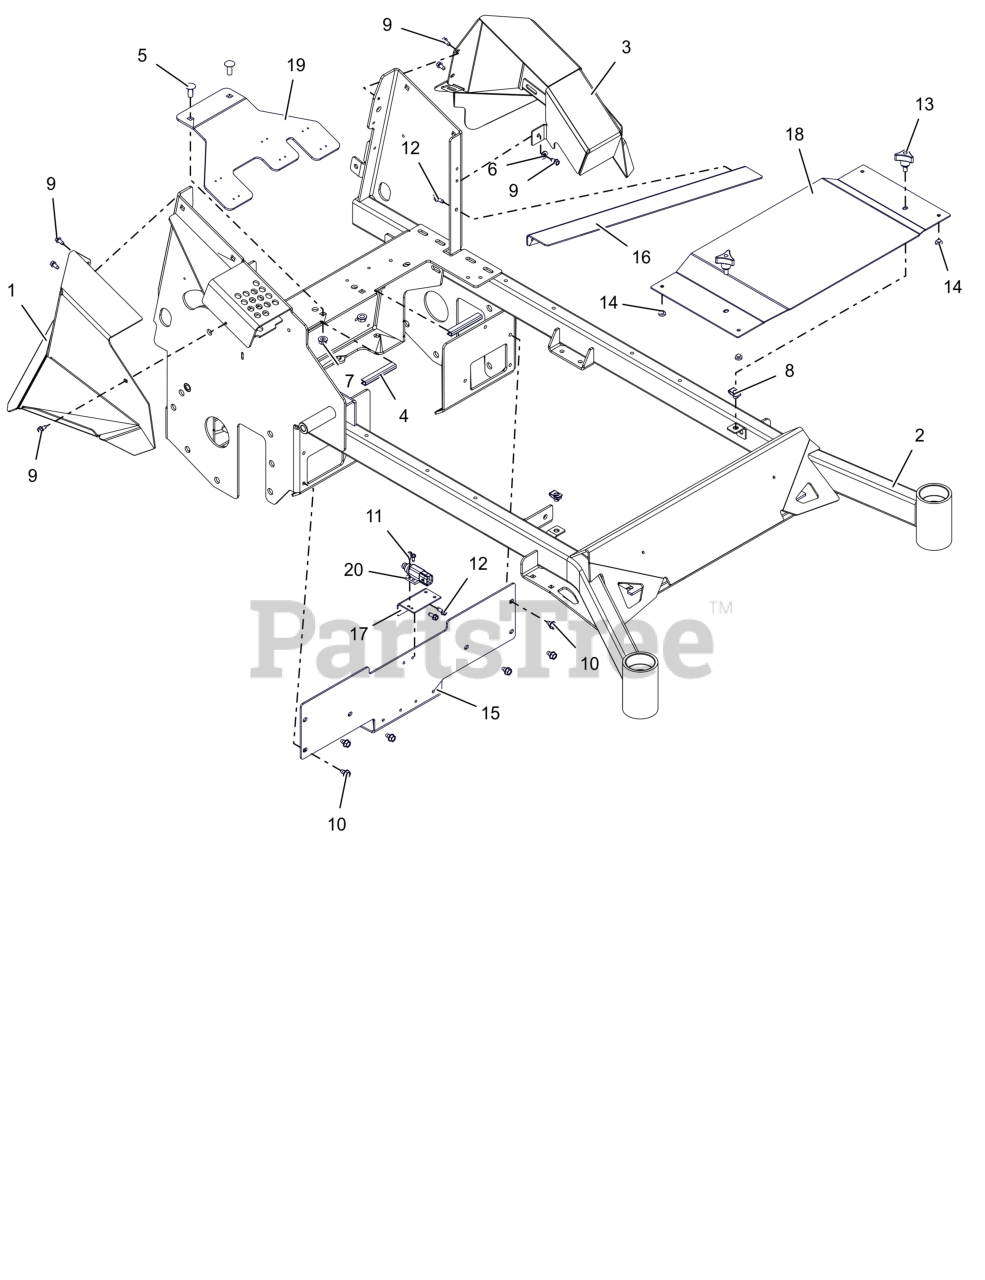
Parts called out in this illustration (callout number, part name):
1	WLDMT, RH FENDER (BLACK)
2	WLDMT- PROSTANCE MAIN FRAME
3	WLDMT, LH FENDER (BLACK)
4	STRIP, COWL
5	BLT,RHSSN .38-16X1.00 G5 ZCC
6	WSHR,FLT .344X.688X.065 ZCC
7	NUT-LK-CTR-FLG .375-16 GF ZCC
8	NUT-CLIP RETAINER 5/16-18X.56
9	SCR-TAP .25-20X.50 HWH ZCC
10	SCR,TAP .312-18X.50 HWH TR ZCC
11	SCR,TAP #10-24X.50 HWH TR ZCC
12	SCR,TAP .25-20X.625 HWH ZCC
13	KNOB,WING STUD 5/16-18 X .75
14	BUMPER GROMMET
15	PLATE- FRONT FRAME
16	BRKT, DRIP EDGE (BLACK)
17	BRKT- LOWER BRAKE RELEASE
19	BRKT, ANDERSON MTG (ORANGE)
20	SWITCH, SEALED PLUNGER
